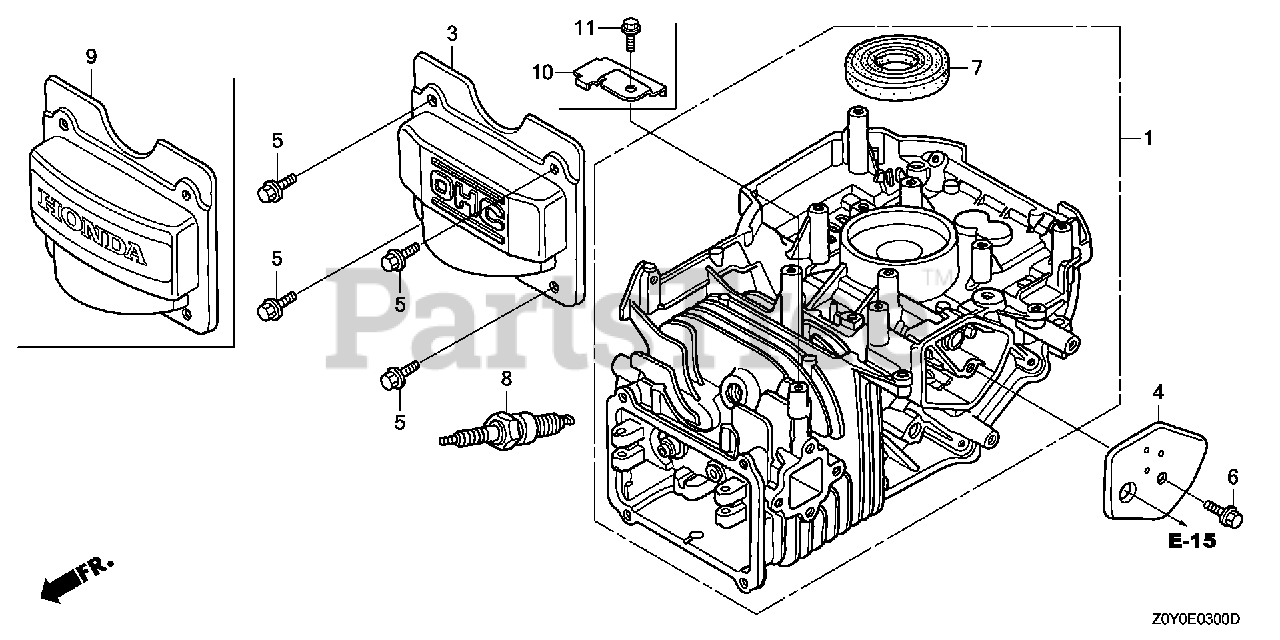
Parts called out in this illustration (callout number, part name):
1	CYLINDER ASSY.
3	COVER, CYLINDER HEAD
4	COVER, BREATHER (Honda Code 5580006). (BREATHER VALVE ASSY.)
5	BOLT, FLANGE (6X12) (CT200)
6	BOLT, FLANGE (6X14)
7	OIL SEAL (25.4X62X6)
8	SPARK PLUG (BPR6ES) (NGK)
